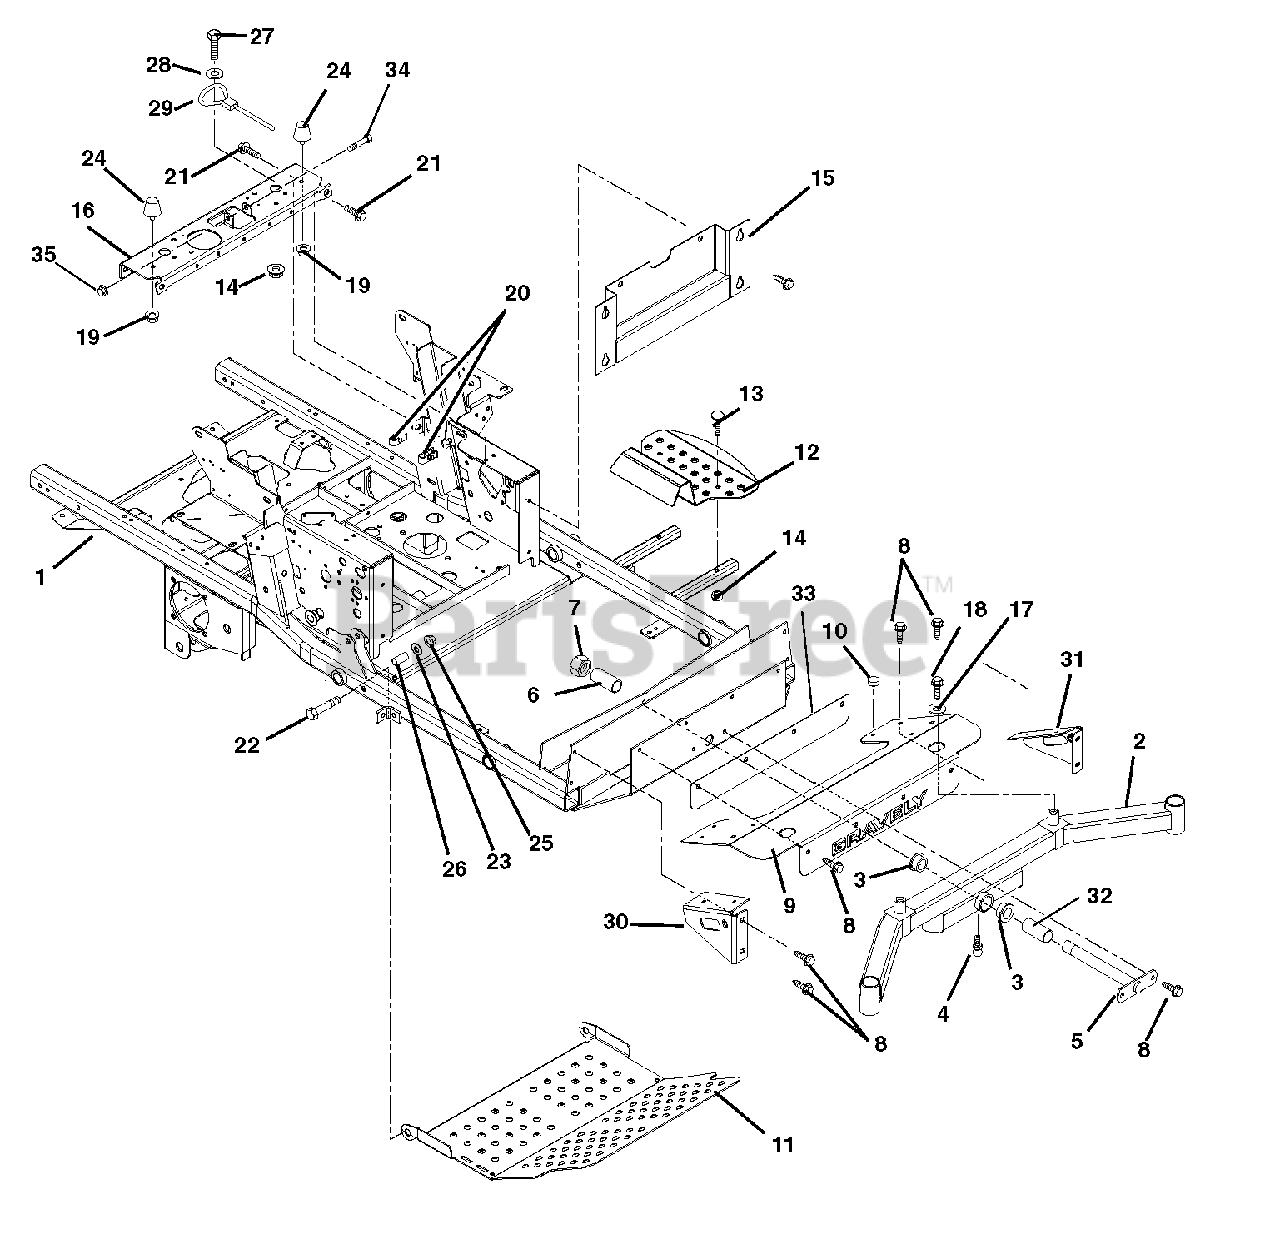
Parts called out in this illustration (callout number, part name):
1	Weldment, Frame
2	Weldment, Axle
3	Bushing, Flange 1.25 x 1.50 x 1.00 x .200
4	Fitting, Lube 45 Degree GM411031
5	Pin, Axle
7	Nut, Locking Nylon 1.00-14
8	Screw, Tapping .38-16 x .75
9	Axle Cover
10	Button, Rubber
11	Panel, Inspection
12	Step, Ingress
13	Bolt, Round Head Square Neck .31-18 x 1.75 Grade 5
14	Nut, Locking Top Flange .31-18
15	Plate, Kick
16	Channel, Cross
17	Washer, Flat Steel .640 x 1.81 x .25
18	Bolt, Hex .50-20 x 1.00 Grade 5
19	Nut, Locking Flange .312-18
20	Nut, Retainer .375-16 x .37
21	Bolt, Serrated Hex Flange Washer Head .38-16 x 1.00
22	Bolt, Hex .50-13 x 3.25 Grade 5
23	Washer, Flat Steel .563 x 1.38 x .109
25	Nut-Locking-Top-Flange .50-13
26	Bushing, Flange .515 x .75 x .275 x 1.12
27	Bolt, Hex .31-18 x .75 Grade 5
28	Washer, Flat Steel .344 x 1.25 x .135
29	Cable, Seat Prop.
30	Weldment, RH Axle Cover Support
31	Weldment, LH Axle Cover Support
32	Spacer, 1.25OD x 1.0ID x 3.63
33	Plate, Backer
34	Bolt, Hex .38-16X3.00 Grade 5
35	Nut, Locking-Top-Flange .38-16
